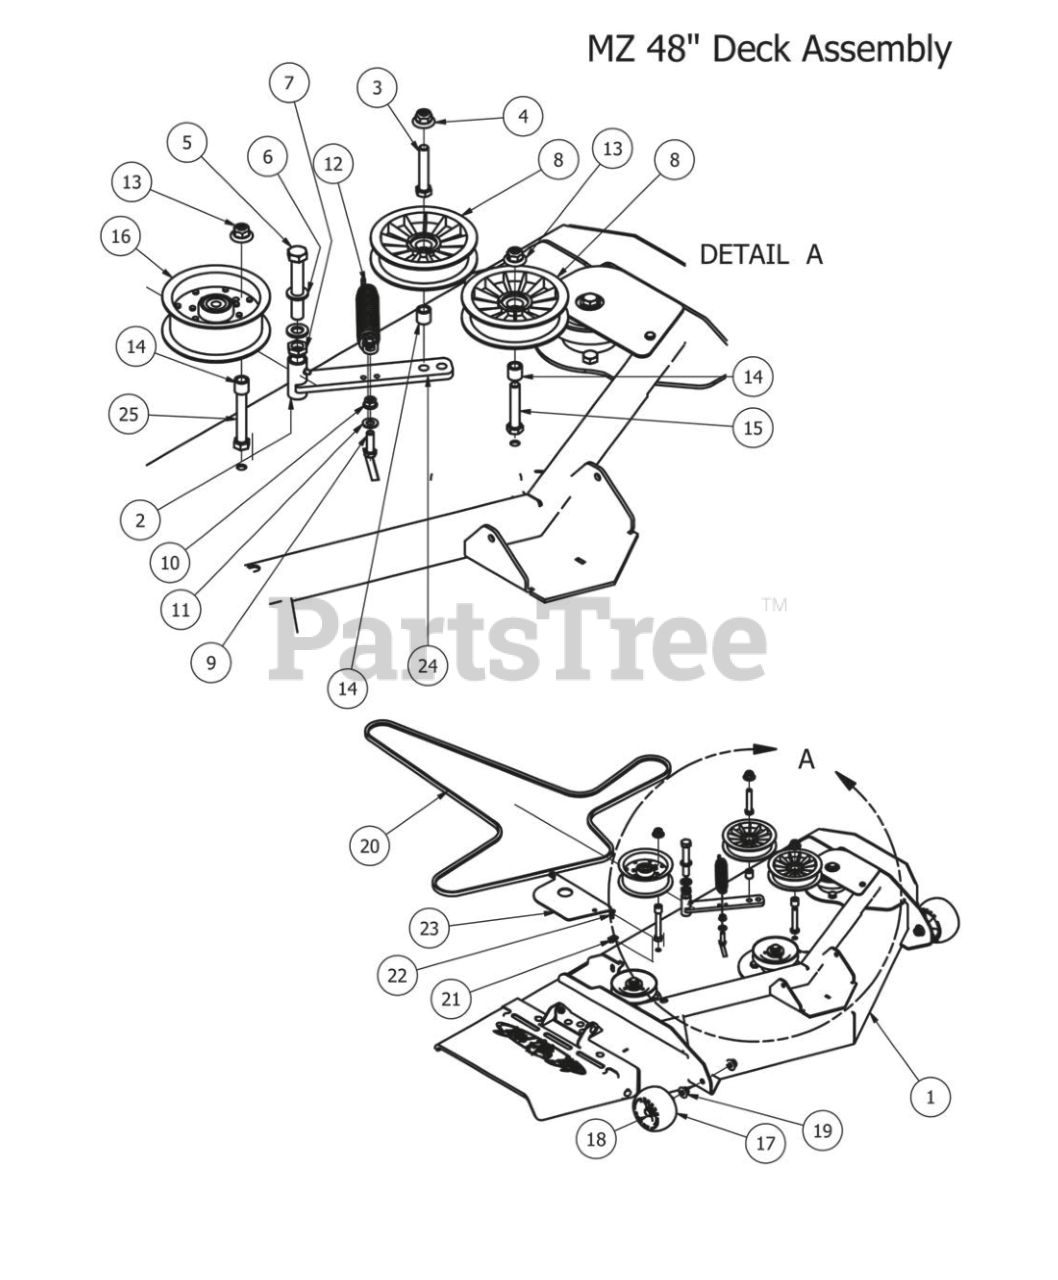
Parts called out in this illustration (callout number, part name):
1	48 MZ Deck
2	Deck Idler arm
3	1/2" x 2 3/4" Hex Bolt
4	1/2-13 Nylon Flange Nut-Orange
5	5/8" x 4" Hex Bolt
6	.635 ID Plastic Washer
7	5/8" Nylock (1/2 Jam)
8	Plastic Idler Pulley
9	3/8" x 1 1/4" Hex Bolt
10	3/8" Nylock Flange Nut
11	3/8" Flat Washer
12	Deck Idler Spring
13	1/2-13 Nylon Flange Nut-Orange
14	3/4 OD x 1/2 ID x 3\4 Length
15	1/2" x 2 3/4" Hex Bolt
16	5 3/4 flat idler-32fI-92-008
17	Deck Wheel
18	1/2 x 3 1/2 Flange Bolt Grade 8
19	1/2-13 Nylon Flange Nut-Orange
20	B128 Deck Belt
21	1/4-20 Cage Nut
22	1/4" x 3/4" Hex Bolt
23	MZ 48 Pulley Cover
24	Parts 2,3,4,8,14 make up the deck idler assembly
25	1/2-13 x 3 1/2 GR 5 Hex Bolt
